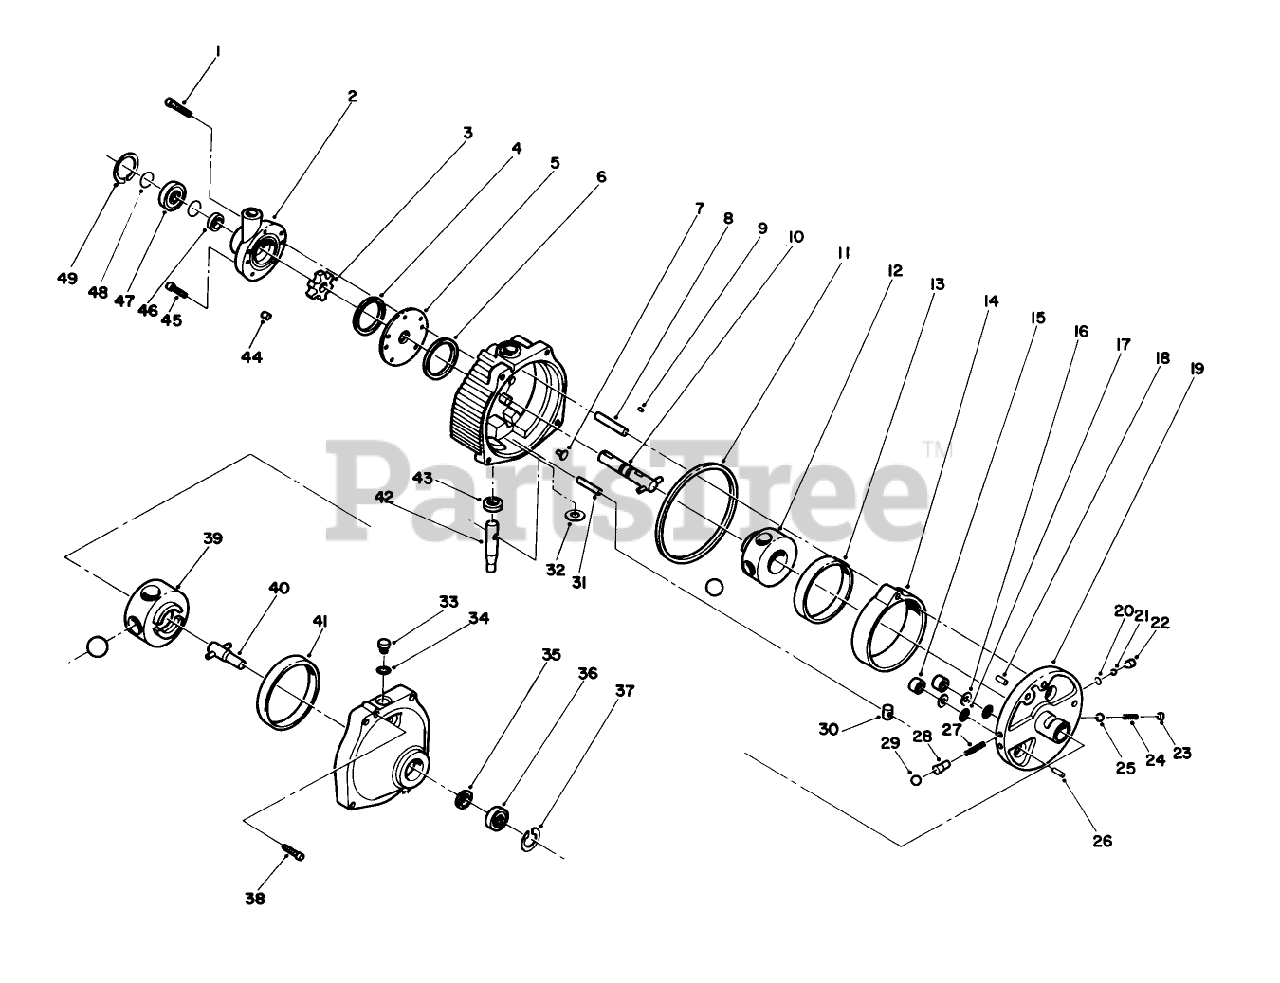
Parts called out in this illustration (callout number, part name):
1	CAPSCREW
2	CHARGE PUMP
3	CARRIER
5	PLATE
7	BUTTON
9	Drive Pin
12	ROTOR
13	Pump Race
14	CAM RING ASM
15	PISTON
17	O-RING
19	PINTLE
24	SPRING
27	SPRING
30	INSERT
31	Dowel
32	Control Shaft Washer
33	PLUG ASM
34	O-RING
39	ROTOR
42	SHAFT KIT
45	SCREW-HH
46	SEAL-OIL
47	BEARING
